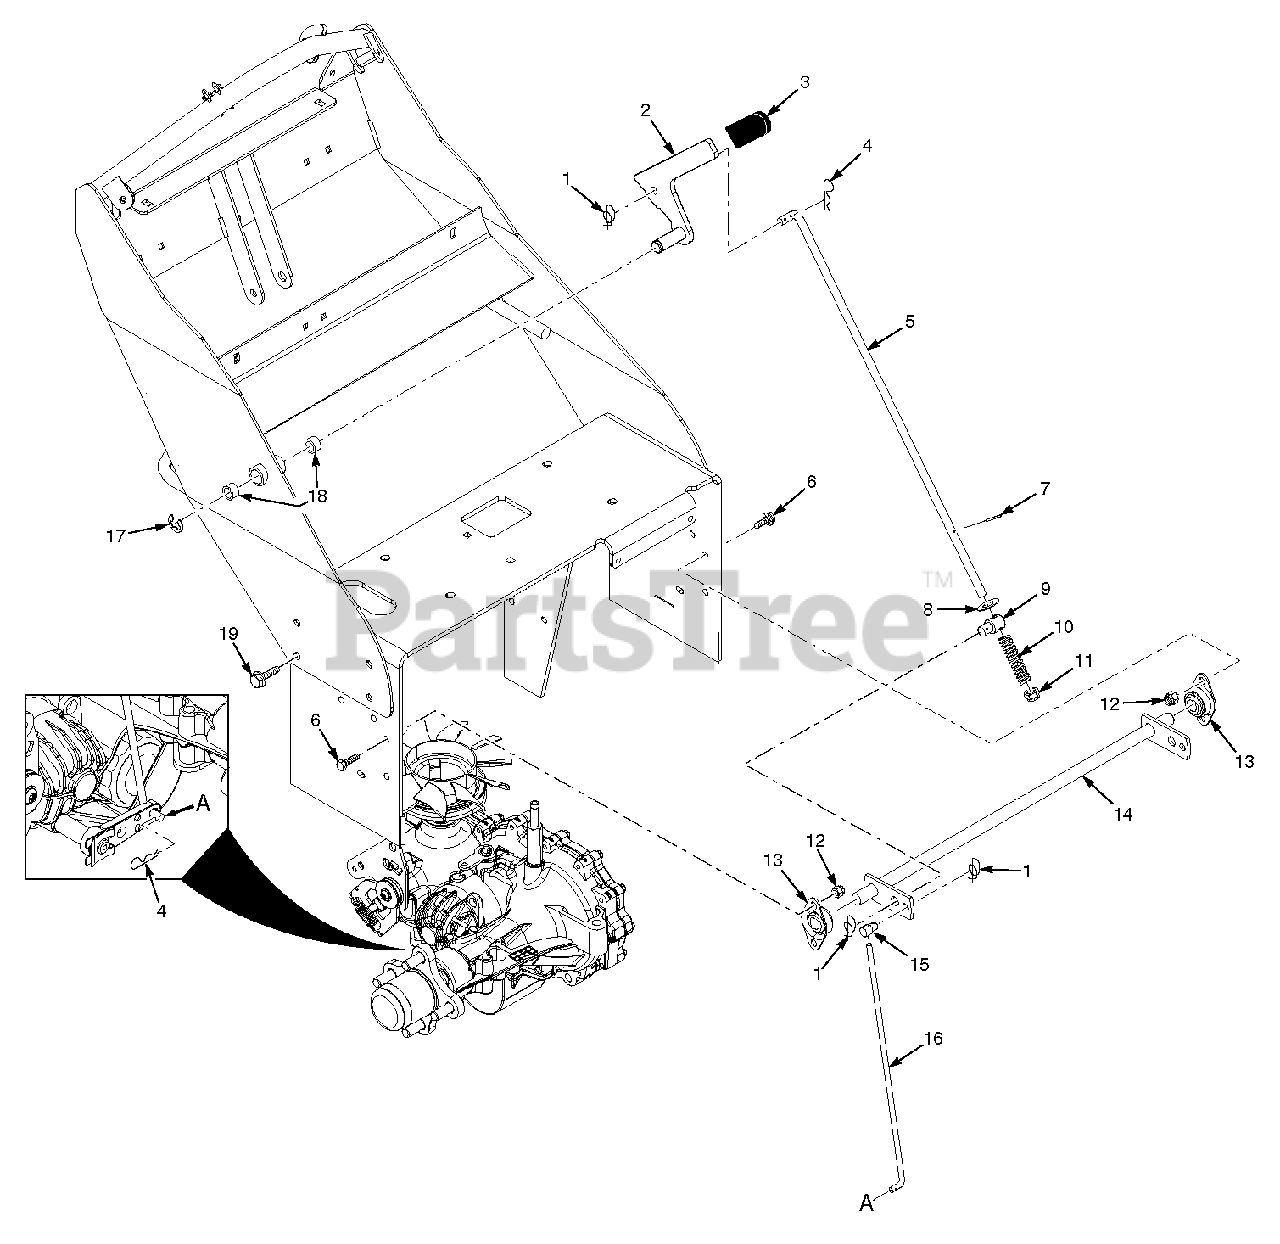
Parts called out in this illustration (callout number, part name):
1	Pin, Rue Cotter 3/8" Dia.
2	Brake Lever w/Grip
3	Grip, Brake Lever
4	Hair Pin, .080 x 1.19"
5	Rod, Brake Linkage
6	Cpscrw, 5/16-18 x 3/4"Serrated Flange HH
7	Cotter Pin, 3/32 x 3/4"
8	Flatwasher, 3/8-.406 x .812 x .065
9	Bushing, Pivot Slide
10	Spring, Brake
11	Nut, Elastic Stop 3/8-24
12	Nut, Elastic Stop 5/16-18
13	Bearing, Self Aligning 5/8" I.D.
14	Weldment, Brake Bellcrank
15	Joint, Swivel
16	Rod, Brake Adjustment
17	Ring, Retaining 5/8" External "E"
18	Bearing
19	Cpscrw, 3/8-16 x 1"Serrated Flange HH
